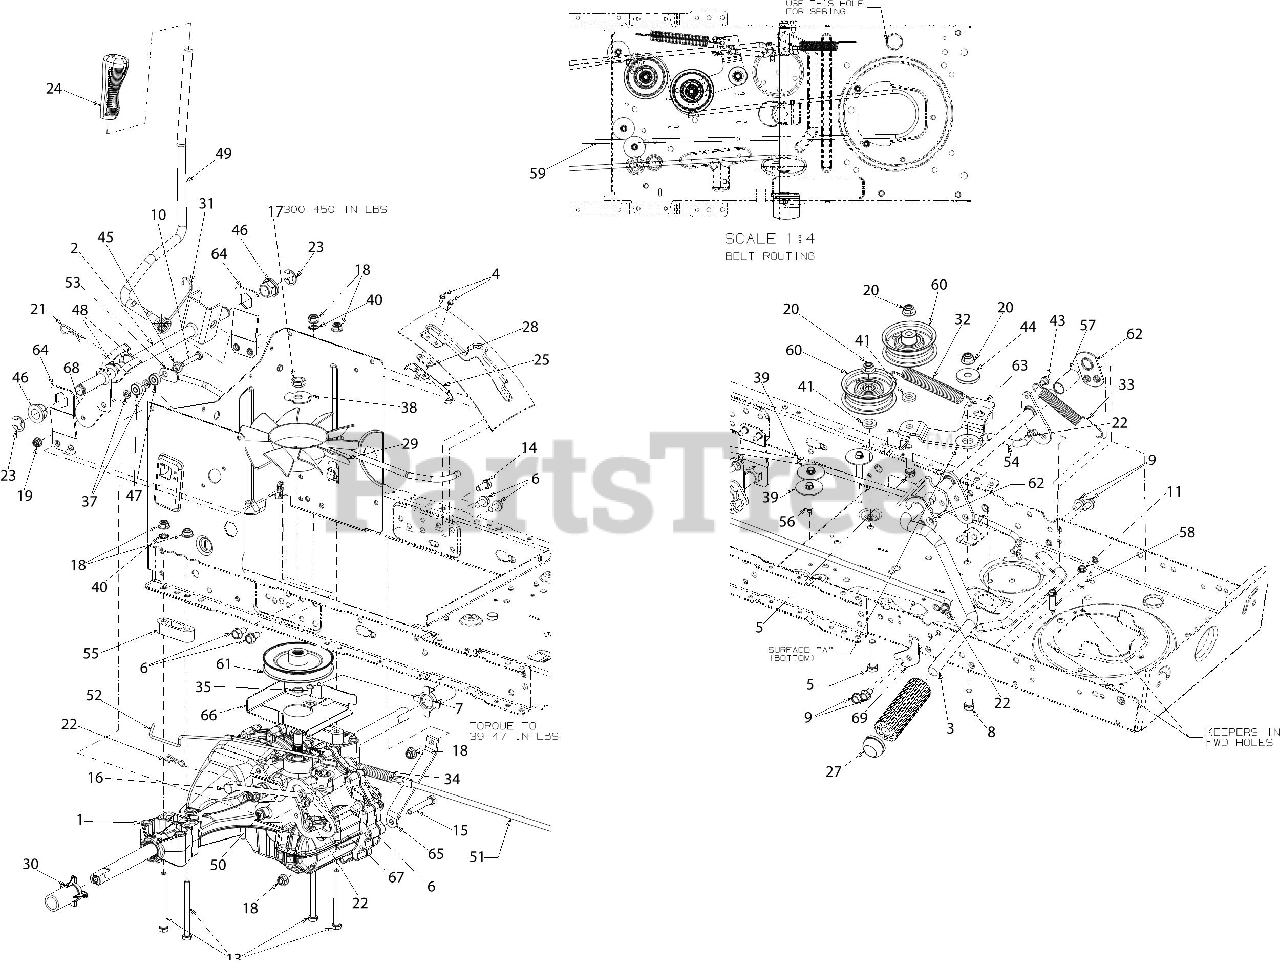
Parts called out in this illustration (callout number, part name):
1	HYDRO TRANSMISSION ASSEMBLY
2	CONTROL HANDLE ASSEMBLY
4	HEX SCREW WASHER HD #8-18 x 0.500
5	HEX SCREW 3/8-16 x 1.75 GR5
6	SCREW 5/16-18 x .750
7	SCREW-#10-24 x .400 SELF TAP
8	SCREW 3/8-16 x 1 GR5
9	SCREW 5/16-18 x .625
10	SCREW 1/4-20 x 1.50 GR.5
11	SCREW 1/4-20 x 1.25
13	SCREW 5/16-18X3.5 GR5
14	SCREW 5/16-18 x .75 GR5
15	SCREW 5/16-18 x 2.0 GR5
16	FERRULE 5/16-24 x .312
17	NUT
18	FLANGE LOCK NUT 5/16-18
19	FLANGE LOCK NUT
21	INTERNAL COTTER PIN
22	BOW TIE COTTER PIN 1/4-5/16
23	E-RING
24	HANDLE GRIP
25	SPRING SWITCH
27	PUSH CAP
28	INSULATOR PLATE
29	HYDRO FAN
30	AXLE SLEEVE .765 ID x 2.11 LG
31	TORSION SPRING
32	EXTENSION SPRING .75 DIA x 6.02LG
33	EXTENSION SPRING .63 x 4.95
34	EXTENSION SPRING
35	WIRE RING
37	LOCK WASHER
38	LOCK WASHER
39	FLAT WASHER .350X1.59X.062
40	WASHER
41	FLAT WASHER
43	SHOULDER SCREW 1/4-20X.50 19"PSH
44	SHOULDER SPACER 1.375 x .380 X.154
45	SHOULDER SPACER
46	FLANGE BEARING
47	BALL BEARING .25 x .6875 x .25
48	SPLIT HEX FLANGE BEARING .628
49	CONTROL HANDLE
50	HYDRO CONTROL ROD
51	BRAKE ROD
52	HYDRO BYPASS ROD
53	HYDRO CONTROL ROD
54	HYDRO DECLUTCHING ROD
55	TRANSAXLE SPACER
56	SPACER:.260 x .372 x 1.420
57	SPACER
58	SPACER
59	V-BELT 4L x 84
60	FLAT IDLER PULLEY 2.75 OD
61	INPUT PULLEY
64	HYDRO HANDLE BRACKET
65	TORQUE BRACKET
66	BELT SUPPORT BRACKET
67	CAM BRACKET
68	PIVOT BRACKET
69	PEDAL STOP PLATE
